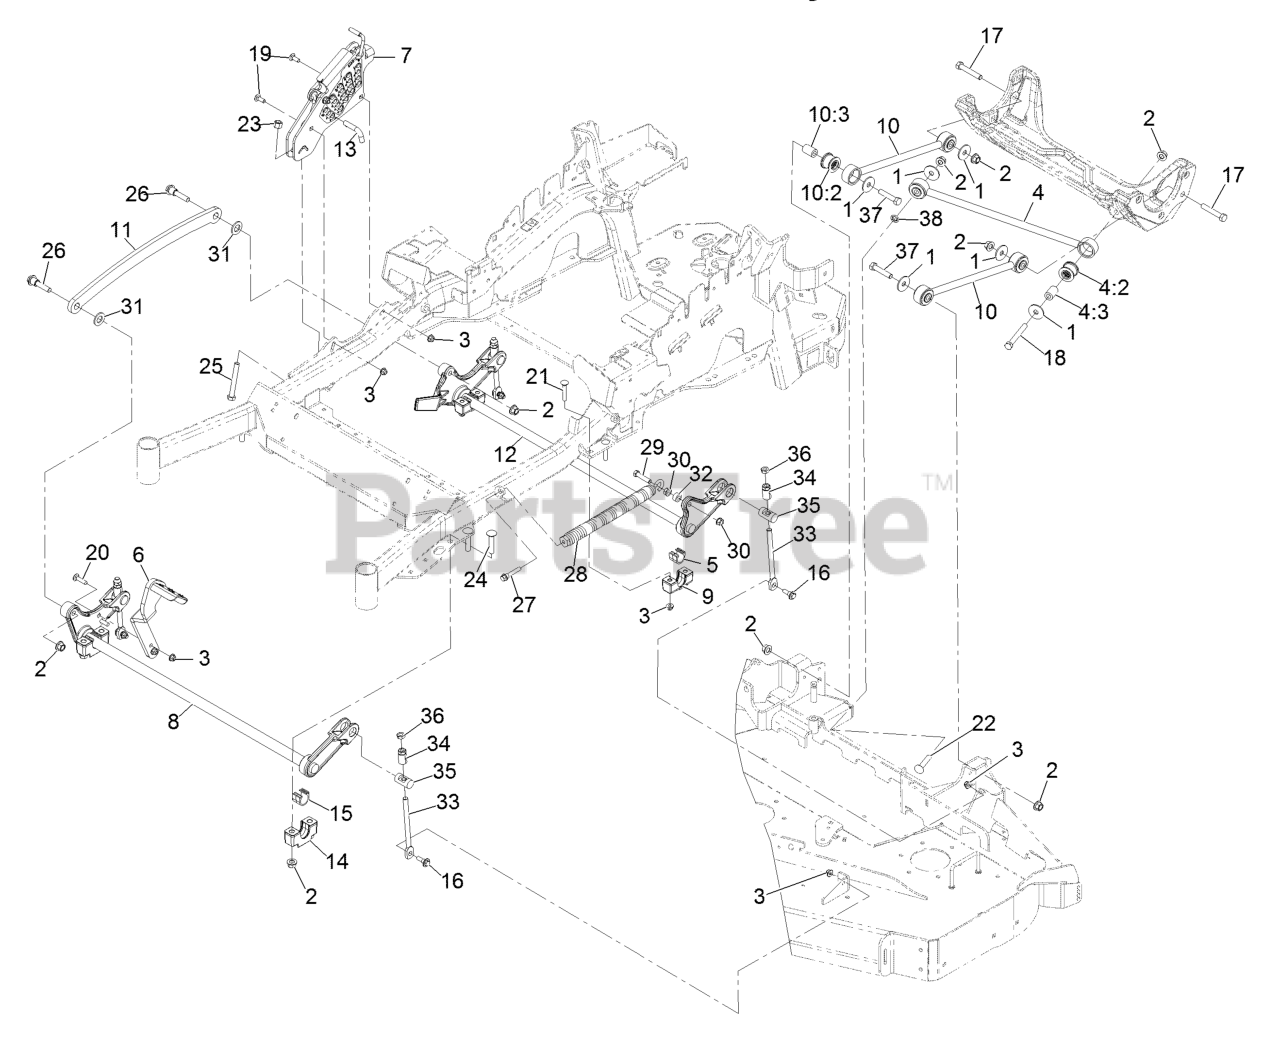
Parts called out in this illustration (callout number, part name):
1	WASHER-THRUST
2	Nut-Lock 1/2-13
3	NUT-HF, NI
4	PANHARD ROD ASM
4:2	BUSHING-SUSPENSION, RUBBER
5	BEARING-CROSS SHAFT, REAR
6	LEVER-FOOT
7	HOC ASM
8	DECKLIFT-FRONT
9	SUPPORT-CROSS SHAFT, BEARING REAR
10	DECK STRUT ASM
10:2	BUSHING-SUSPENSION, RUBBER
11	LINK-LIFT, DECK
12	LIFT-DECK, REAR
13	PIN-HOC
14	SUPPORT-CROSS SHAFT, BEARING
15	BEARING-CROSS SHAFT, FRON
16	SCREW-SHOULDER, HHF
17	SCREW-HH
18	SCREW-HH
19	BOLT-CARR
20	SCREW-CARR
21	Bolt-Carriage 3/8-16 X 2 1/4
22	SCREW-CARR
23	NUT-LOCK, NI
24	Bolt-Carriage 1/2-13 X 2 1/2 Spl Neck
25	BOLT-TAP
26	SCREW-HHF, SHOULDER
27	BOLT-SHOULDER
28	SPRING-EXTENSION
29	SCREW-HH
31	WASHER-FLAT
33	LINK-ADJUSTER, DECK LIFT
34	ADJUSTER-LIFT, DECK
35	TRUNNION
36	NUT-JAM
37	SCREW-HH
38	NUT-PUSH
